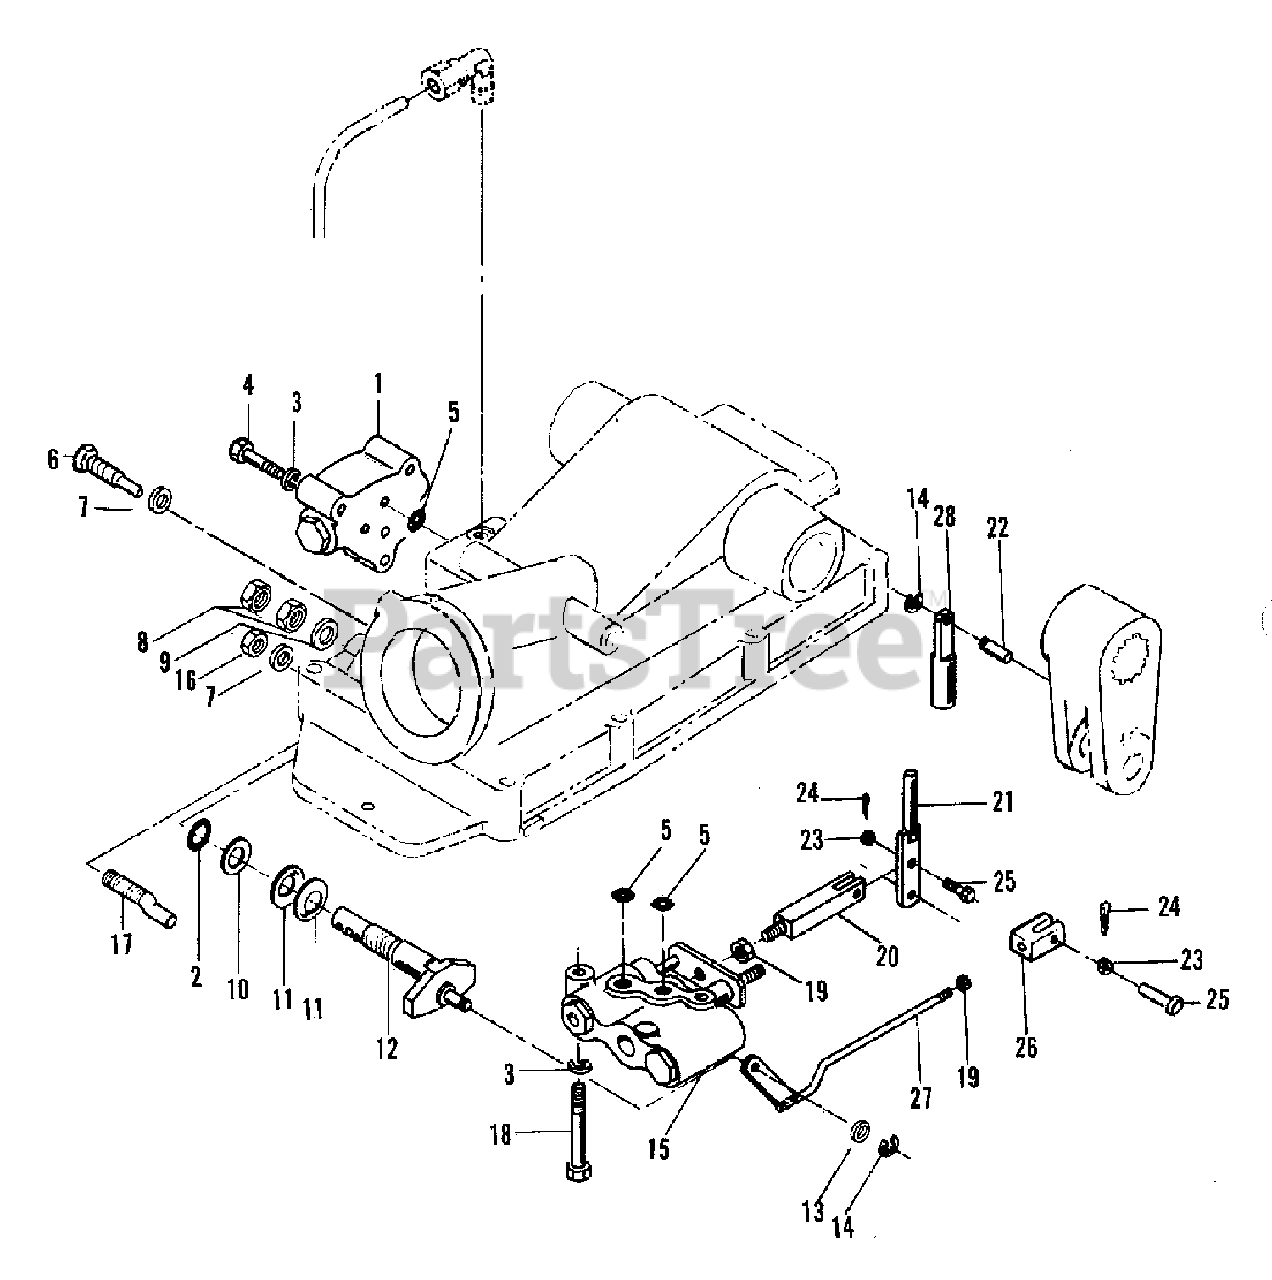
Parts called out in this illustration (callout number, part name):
1	COVER ASSEMBLY (Refer to COVER ASSEMBLY Group for Components)
3	LOCKWASHER, M8
4	CAPSCREW, M8 x 20
6	BOLT, stopper
7	WASHER, seal
9	WASHER, thrust
10	WASHER, thrust
11	WASHER, countersunk
12	ROD, lever
15	VALVE, control (Refer to VALVE Group for Components)
17	BOLT, adjusting
20	TURNBUCKLE
21	LINK, working (A)
22	ROD, guide
24	PIN, cotter
26	TURNBUCKLE
27	LINK, working (B)
28	GUIDE, link (A)
